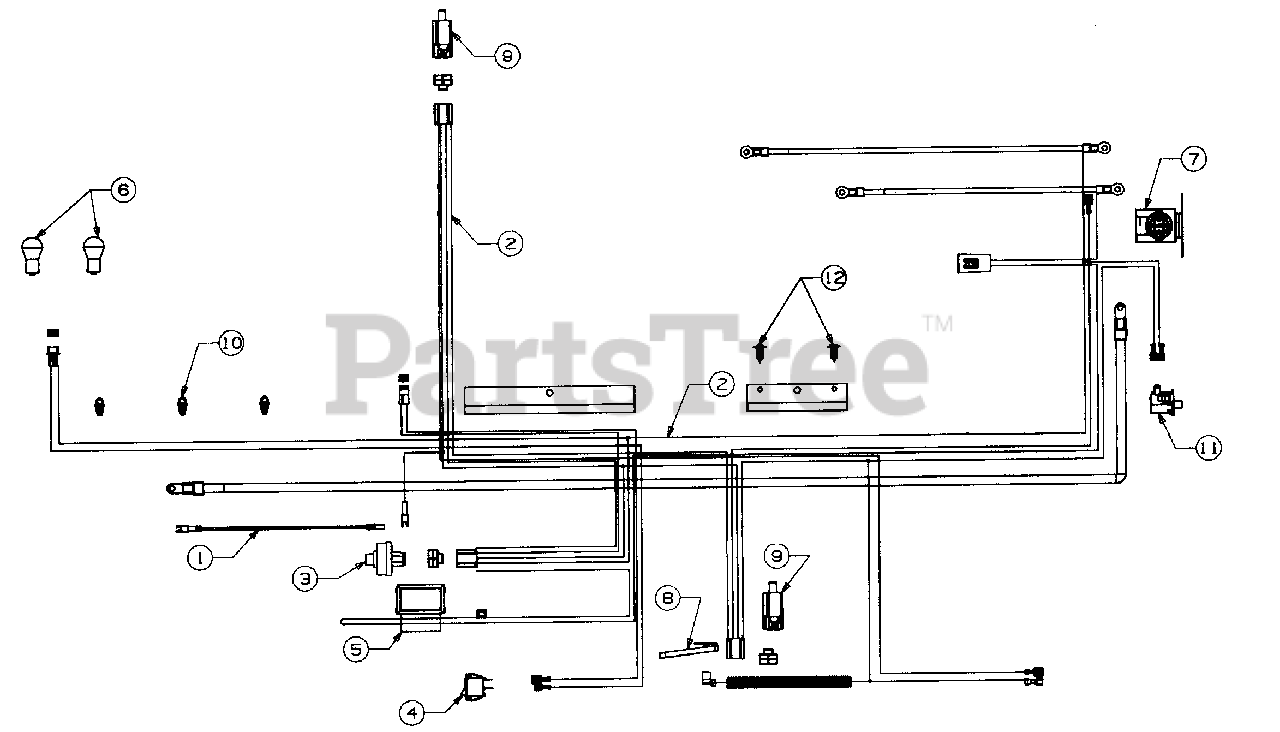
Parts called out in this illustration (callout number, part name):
1	Harness Adapter (Mag.)
2	Wire Harness
3	Ignition Switch
4	Light Switch
5	Ammeter
6	Bulb (Headlight)
7	Solenoid
8	Spring Switch (Reverse)
9	Safety Switch (Clutch)
10	Wire Retainer Clip
11	Safety Switch
12	Ratchet
